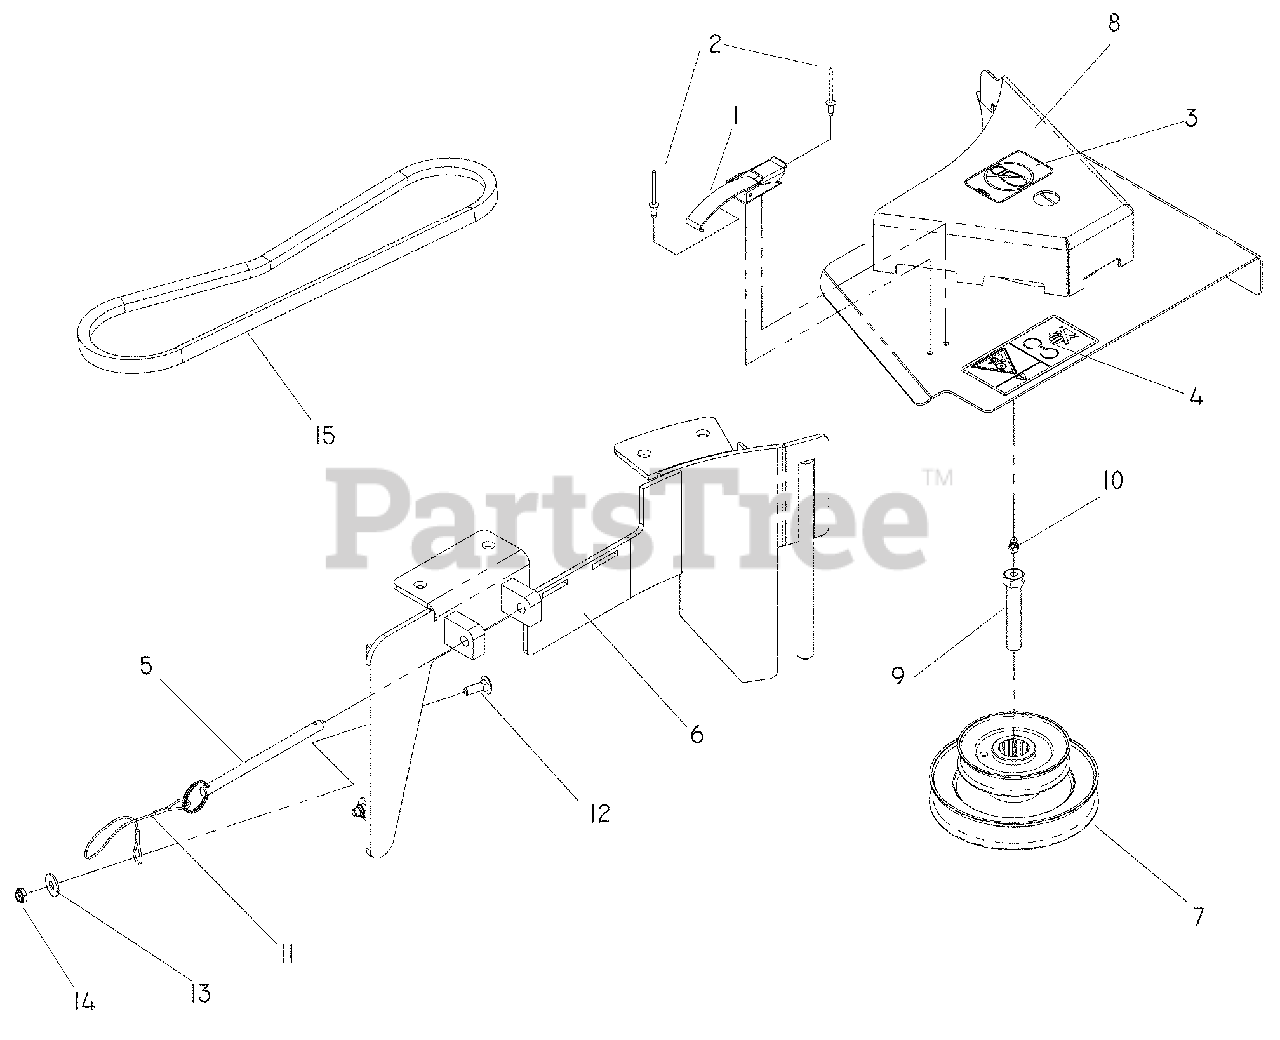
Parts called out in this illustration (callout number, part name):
1	DRAW LATCH
3	DECAL, NO STEP
4	DECAL, DANGER BELT DRIVE
6	BLOWER DECK PLATE, 52
7	PULLEY, STACKED 52
8	SHIELD W/DECALS & LTCH, 52
9	HCS, 7/16 -20 X 2½, GR8
10	ZERK
12	RHSNB, ¼ -20 X ¾, GR2
13	WASHER, ¼
14	NUT ¼ -20, JAM, NYLOC
